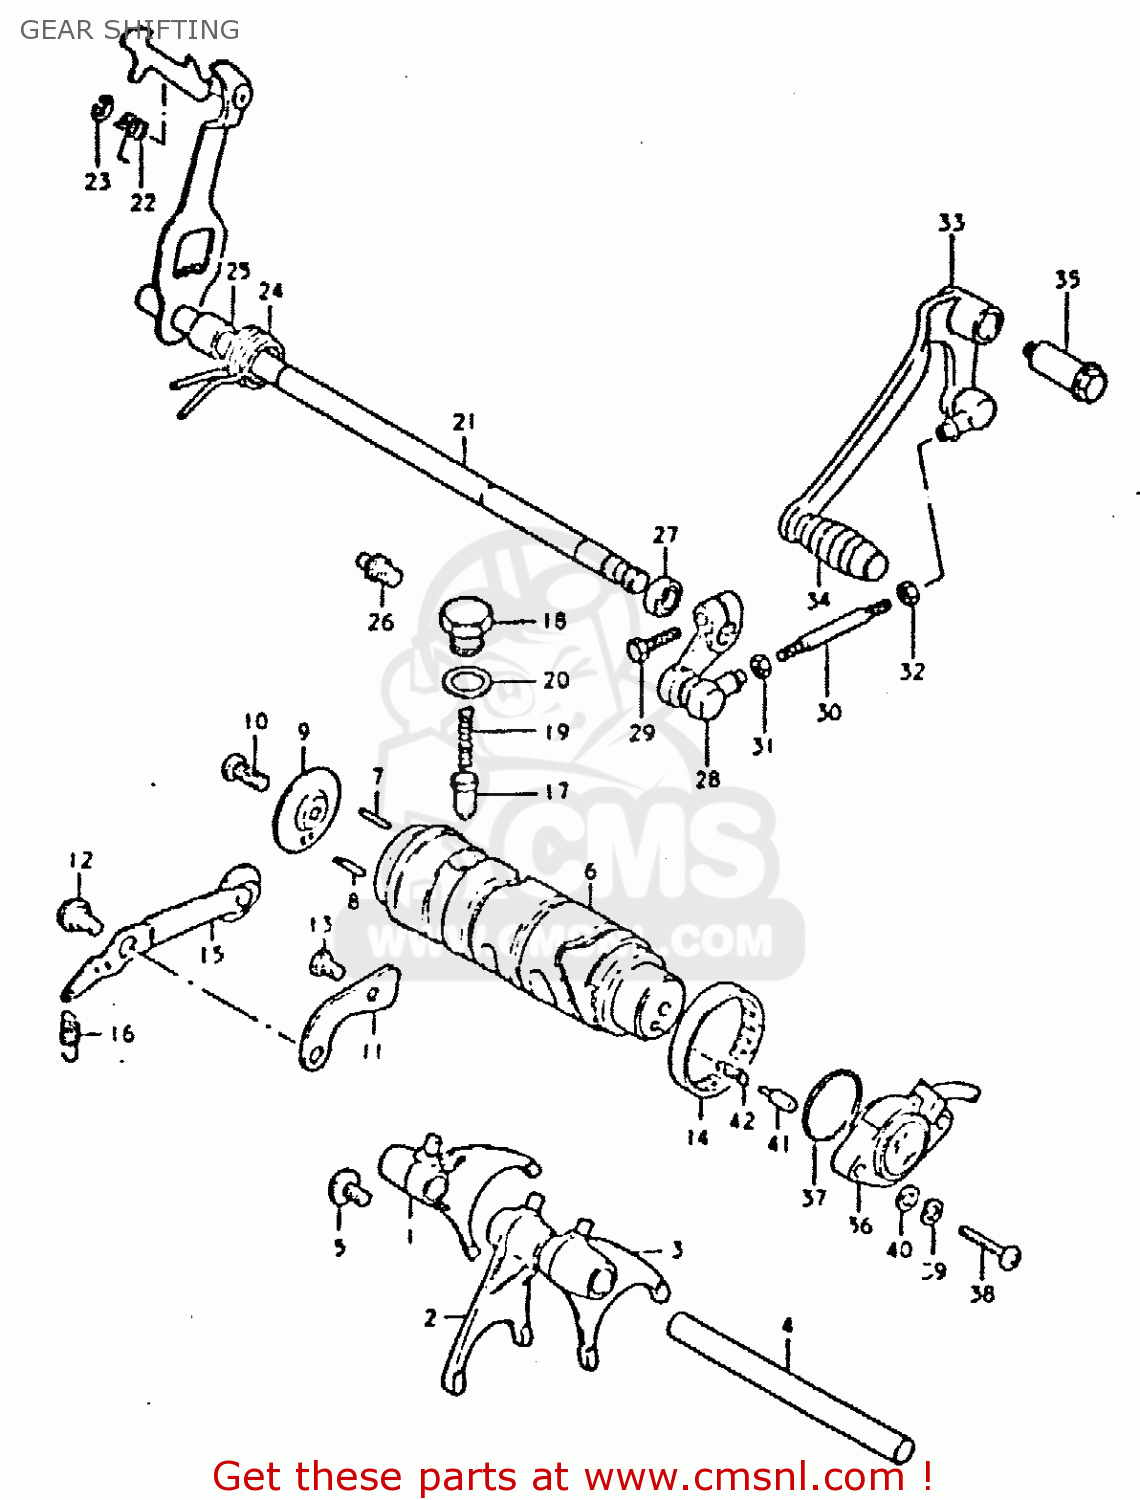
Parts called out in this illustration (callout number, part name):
1	FORK,GEAR SHIFT NO.1
2	FORK,GEAR SHIFT NO.2
3	FORK,GEAR SHIFT NO.2
4	SHAFT,GEAR SHIFT FORK
5	SCREW
6	CAM,GEAR SHIFT
7	PIN(4X18.5)
8	PIN
9	RETAINER,GEAR SHIFT CAM DR PIN
10	SCREW
11	GUIDE,GEAR SHIFTING CABLE
12	BOLT
13	BOLT, UPPER
14	BEARING(40X47X12)
15	STOPPER,GEAR SHIFT CAM NO.1
16	SPRING
17	STOPPER,GEAR SHIFT CAM NO.2
18	HOLDER,GEAR SHIFT CAM STOP SPR
19	SPRING
20	GASKET(14X19.2X2) (NAS)
21	SHAFT,GEAR SHIFT
22	SPRING
23	E RING
24	SPRING
25	SPACER(12X20X15.3)
26	STOPPER,GEAR SHIFT CAM
27	OIL SEAL
28	ARM,GEAR SHIFT LINK
29	BOLT
30	ROD,GEAR SHIFT LINK
31	NUT
32	NUT
33	LEVER ASSY,GEAR SHIFT
34	RUBBER,GEAR SHIFT PEDAL
35	SHAFT,GEAR SHIFT LEVER
36	TERMINAL BASE ASSY,GEAR SHIFT
37	O-RING (D:2.4 ID:26.2)
38	SCREW 5X20
39	LOCK WASHER
40	WASHER
41	PIN(5X15.5)
42	SPRING
